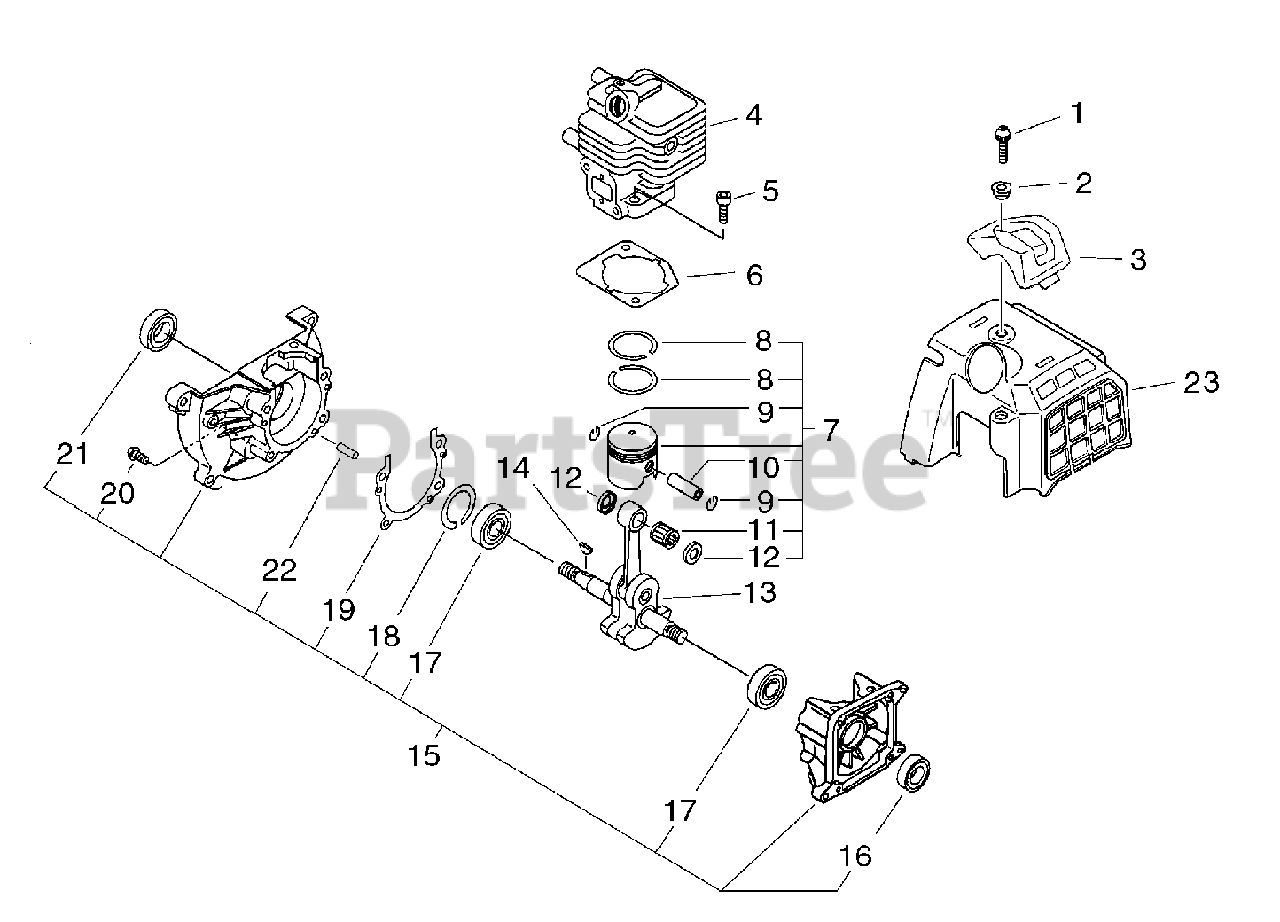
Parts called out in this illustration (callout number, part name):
1	Screw 5x22
2	Collar,5
3	Guard, Top
4	Cylinder
5	Bolt, H.S. 5x22
6	Gasket, Cyl. Base
7	Piston kit
8	Ring, Piston
9	Circlip, Piston Pin
10	Pin, Piston
11	Bearing,Needle 8
12	Spacer, Piston Pin
13	Crankshaft
14	Key, Woodruff
15	Crankcase kit
17	Bearing, Ball 6001
18	Circlip 28
19	Gasket, Crankcase
20	Screw 5*25
21	Oilseal Iscd 12x28x7
22	Pin,Straight 4
23	Cover,Cylinder
